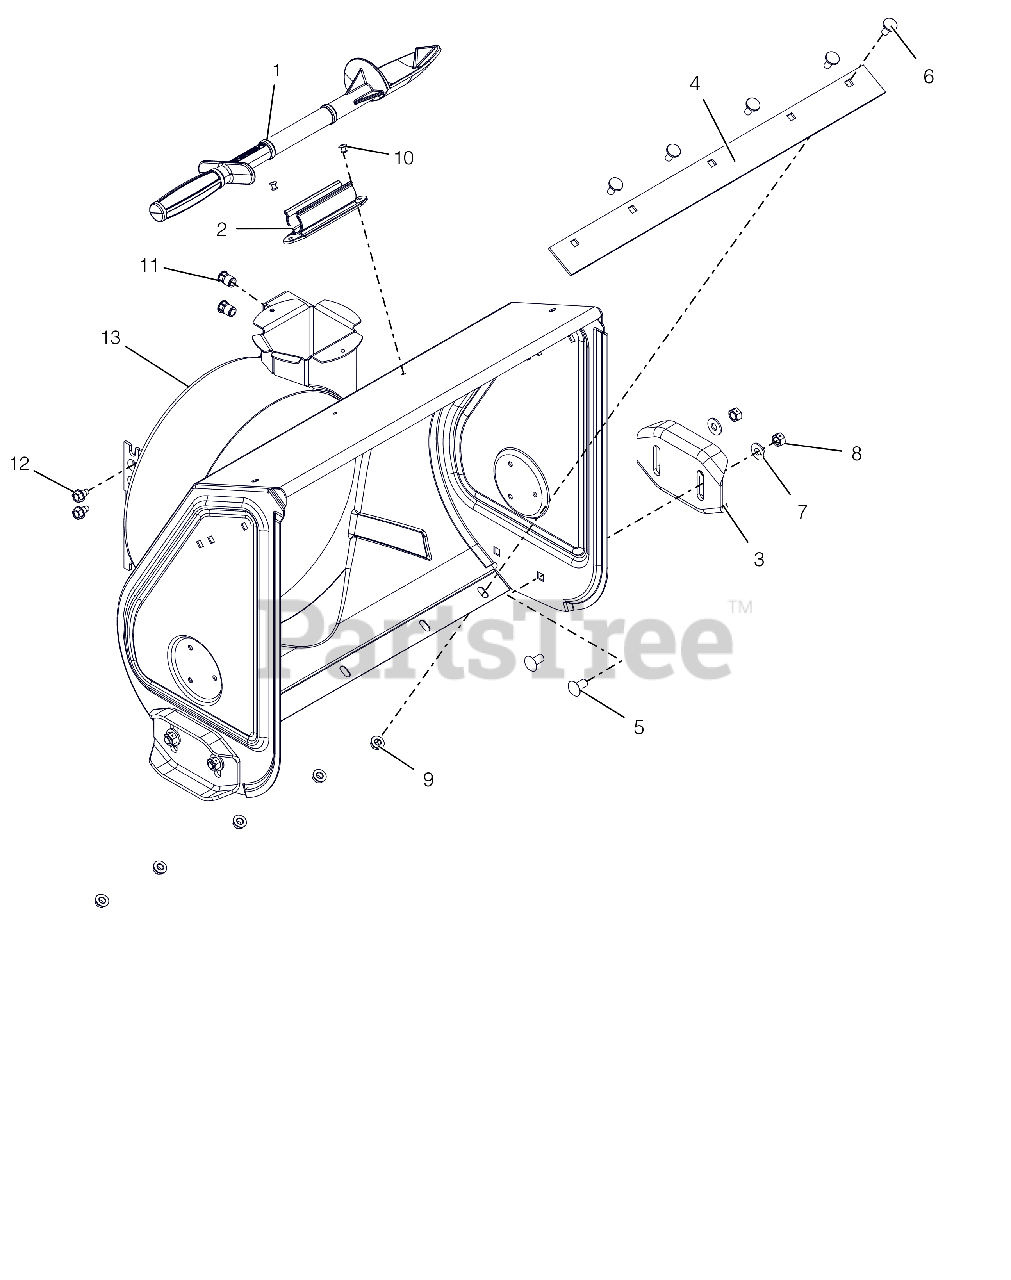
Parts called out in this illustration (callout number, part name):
1	DEVICE, SNOW CLEAN OUT
2	MOUNT, SNOW CLEAN OUT
3	SKID SHOE, REVERSIBLE - ORANGE
4	SCRAPER BLADE, 22" COMPACT
5	@BLT-RHDSSQNK .38-16X.75 G5YZ
6	BOLT, MODIFIED HEAD CARRIAGE
7	@WSHR-FL-STL.38X.875X.083 YWZC
8	@NUT-LK-CTR .38-16 YWZC
9	@NUT-LK-TOP-FLG .31-18 YWZC
10	RVT-POP .187 YZ
11	NUT, THREADED INSERT .38-16
12	@SCR-TAP .31-18X.50 HWH TR YWZ
13	BLOWER HOUSING, 22" HI ORANGE
